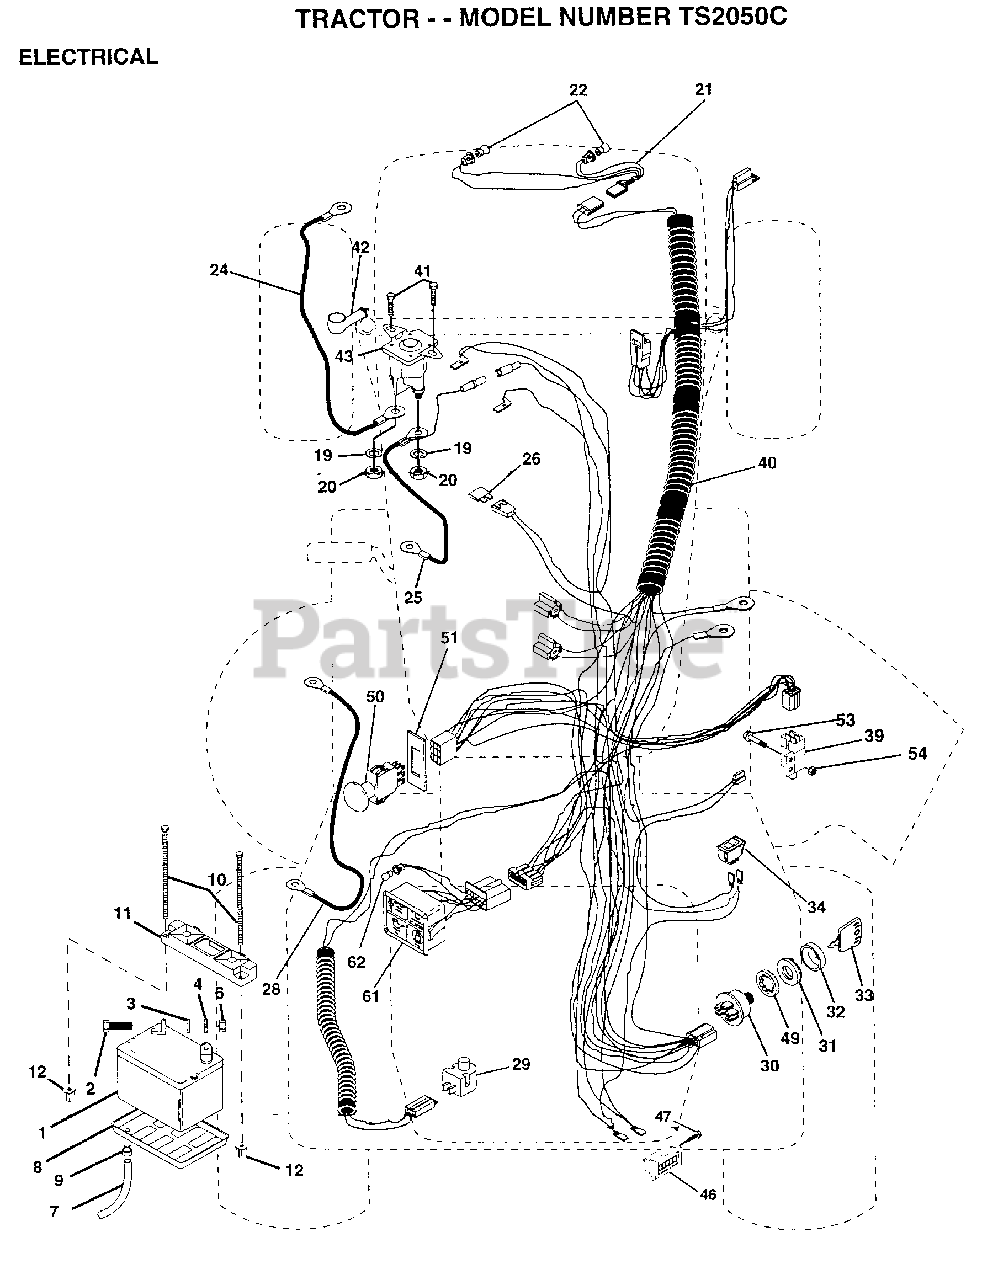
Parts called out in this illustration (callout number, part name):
2	BOLT LT
3	LOCKWASHER
4	WASHER
7	"DRAIN TU T, BATT"
8	"TRAY T, BATTERY"
9	HOSE CLAMP T
20	NUT
21	"HARNESS,LIGHT SOC"
22	HEADLAMP BULB
24	CABLE.BATY.22.RED
25	CABLE.BATRY.4GA.
26	FUSE HYT
28	CABLE.BATRY.4GA.
29	SWITCH SEAT
32	COVER KEY SWITCH
33	KEY MLD GEN DELTA
34	SWITCH LT
39	SWITCH INTERLOCKT
40	HARNESS.IGNITION
41	SCREW
46	HOUR METER T
47	SCREW
49	WASHER PINNED
51	RING RETAIN PTO
53	SCREW
54	"NUT,KEPS"
61	LIGHT.PKG.ASM.
62	BULB LIGHT T
